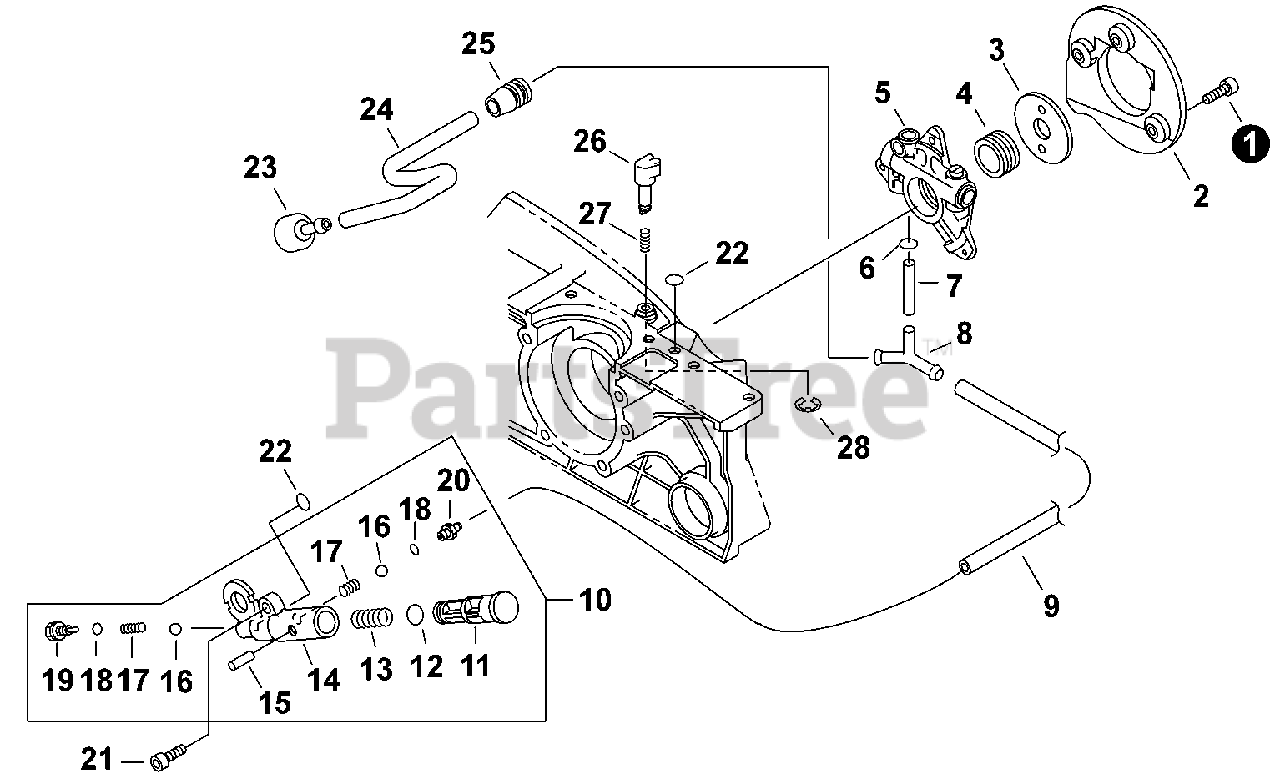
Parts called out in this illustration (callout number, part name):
1	BOLT 4×14
2	COVER, OIL PUMP
4	GEAR, WORM
5	AUTO-OILER ASSY
6	CLIP Ø6.5MM
7	PIPE, OIL 3×6×20
8	CONNECTOR, PIPE
9	PIPE 3×6×210L BLACK
10	OIL PUMP ASSY
11	PISTON, OIL PUMP
12	O-RING 7 MM
14	BODY, OIL PUMP
15	PIN, SPRING 2×16
16	VALVE, BALL
17	SPRING, COMPRESSION
19	ADAPTOR, OIL PUMP
20	CONNECTOR, PIPE
21	BOLT 5×20
22	O-RING 3
23	FILTER, OIL
24	PIPE, OIL
28	E-RING 3
